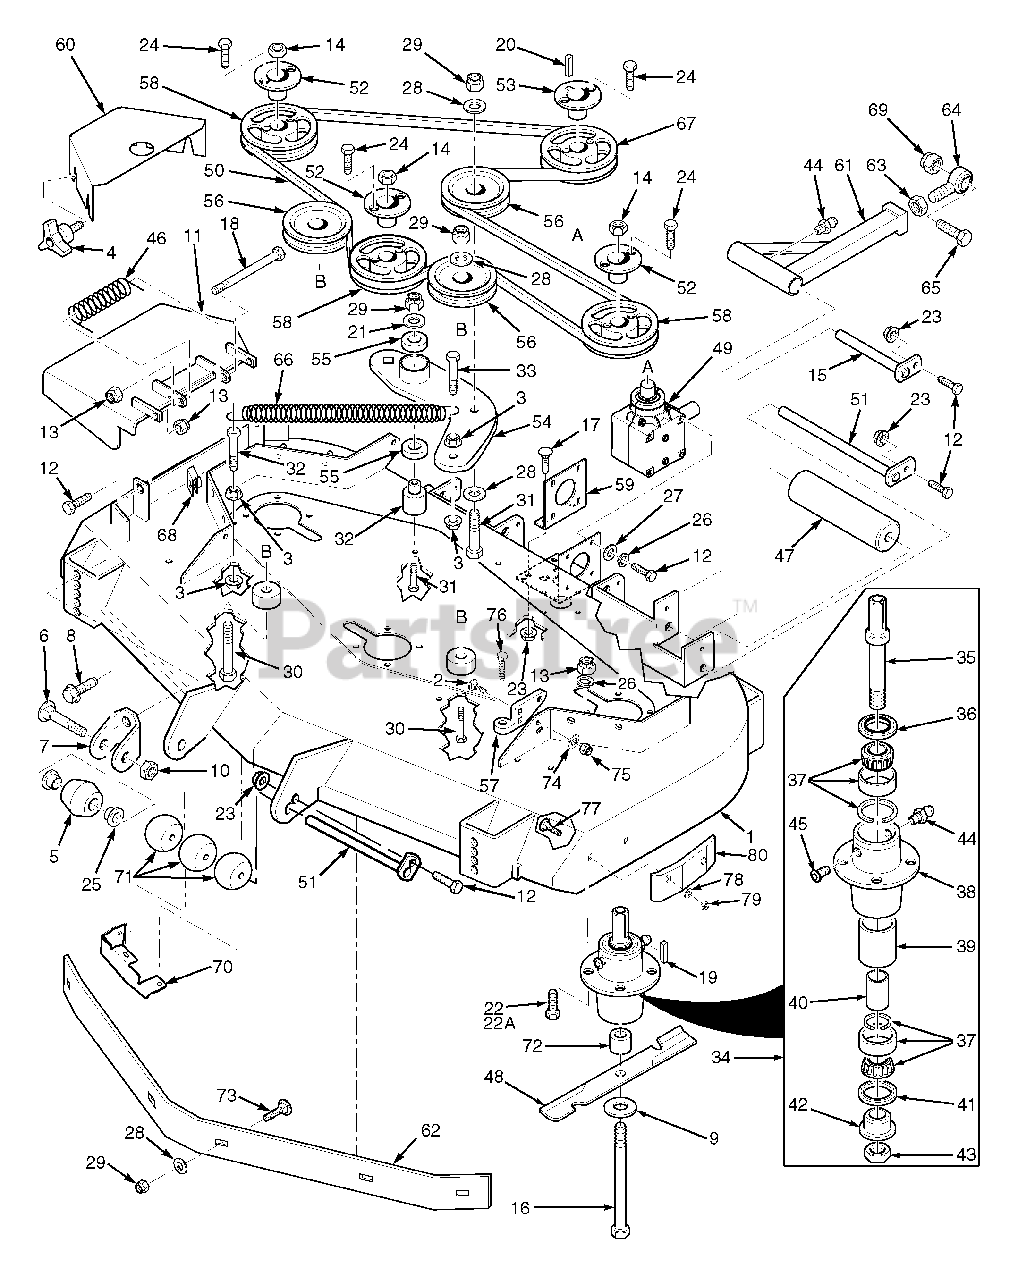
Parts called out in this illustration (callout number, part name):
1	Cutter Deck, 72" Advantage
2	Bolt, Carriage 7/16-14 x 1-1/4"
3	Nut, Hex Serrated Flange 3/8-16
4	Wing Nut, 3/8-16
5	Anti-Scalp Wheel
6	Bolt, Carriage 3/8-16 x 4"
7	Anti-Scalp Wheel Bracket
8	Bolt, Hex Serrated Flange 3/8-16 x 1"
9	Flatwasher, 5/8" Hardened
10	Locknut, 3/8-16 Center Lock
11	Discharge Chute, 72" Adv.
12	Bolt, Hex Head 5/16-18 x 1.75" (Front)
13	Nut, Hex Elastic Stop 5/16-18 Grade 8
14	Nut, 5/8-11 UNC
15	Push Arm Shaft
16	Bolt, Hex Head 5/8-11 x 9.50"
17	Bolt, Carriage 5/16-18 x .75"
18	Bolt, Hex Head 5/16-18 x 4.75"
19	Key, 1/4 x 1/4 x 2"
20	Key, 1/4 x 1/4 x 1.25"
21	Flatwasher,3/8-.39 x .938 x .105 HD
22	Bolt, Hex Head 5/16-18 x 1-3/4"
23	Nut, Hex Serrated Flange 5/16-18
24	Bolt, Hex Head 1/4-20 x 1" Grade 8
25	Bushing, .376 I.D. Oilite
26	Lockwasher, 5/16"
27	Flatwasher, 5/16" (.375 x .875 x .083)
28	Flatwasher, 3/8" (.391 x .938 x .105)
29	Nut, Hex Elastic Stop 3/8-16
30	Bolt, Hex Head 3/8-16 x 3-1/4"
31	Bolt, Hex Head 3/8-16 x 3"
32	Pivot, Idler - Short
33	Bolt, Hex Head 3/8-16 x 1.50" Grade 8
34	Spindle Assembly
35	Spindle Shaft
36	Seal, Top
37	Bearing Assembly
38	Spindle Housing
39	Spacer, Outside
40	Spacer, Inside
41	Seal, Bottom
42	Spindle Bushing, Bottom
43	Nut, Special 1 - 1/16-18
44	Grease Fitting
45	Relief Fitting, Tapered Spindle
46	Spring, Discharge Chute
47	Guide, Roller
48	Cutter Blade, 24.5" 72"
49	Gearbox Assembly, Deck Drive
50	Belt, Cutter Deck Drive, 72"
51	Roller Shaft
52	Tapered Hub, 1-1/8" Bore
53	Tapered Hub, 1" Bore
54	Idler Arm, Cutter Deck
55	Bearings, Ball
56	Pulley, Idler
57	Lever Assembly, Deck Level
58	Pulley, 6.95 O.D. - 72"
59	Mounting Plate, Gearbox
60	Belt Cover, LH - 72"
61	Pusharm
62	Baffle, Custom Cut 72A
63	Nut, Hex Head 5/8-18 UNF
64	Rod End, 5/8" Male RH Thread
65	Bolt, Hex Head 5/8-11 x 4-1/2"
66	Spring, Cutter Deck
67	Pulley, 6.35 O.D. - 72"
68	U-Nut, 3/8-16
69	Nut, Hex Elastic Stop 5/8-11
70	Discharge Baffle 72"
71	Wheel, Anti-Scalp
72	Spacer, Spindle Bottom
73	Bolt, Carriage 3/8-16 x 1"
74	Flatwasher, 7/16-.500 x 1.25 x .083
75	Nut, Elastic Stop 7/16-14
76	Bolt, Deck Adjust
77	Bolt, Carraige 5/16-18 x 3/4"
78	Flatwasher, 5/16"
79	Nut, Center Lock 5/16-18
80	Wear Pad
04001.11	Bolt, Hex Head 5/16-18 x 150" (Rear)
